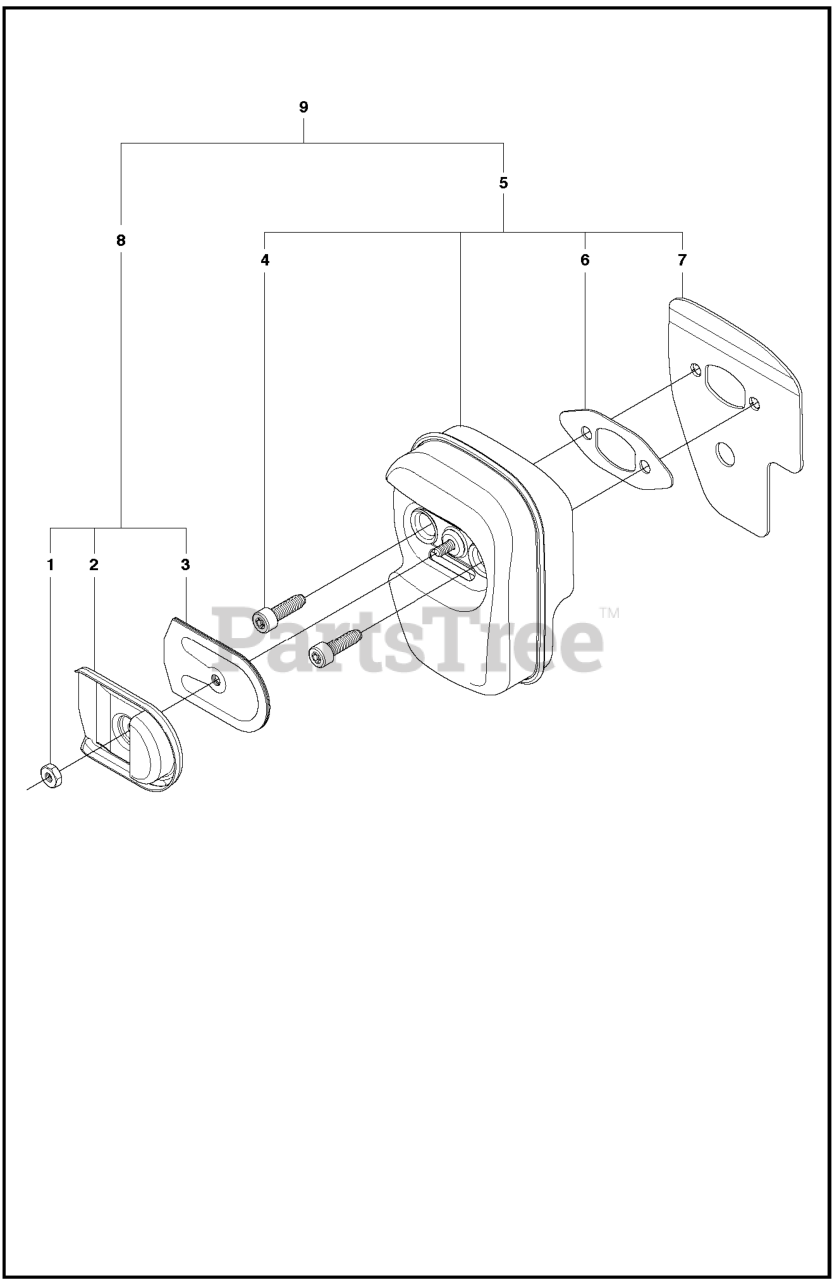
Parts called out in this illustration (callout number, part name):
1	NUT 10MM BRASS
2	EXHAUST PLATE
3	SCREEN ARRESTOR
4	SCREW MUFFLER
5	MUFFLER ASSY
6	GASKET
7	PLATE
8	KIT SPARK ARRESTOR
9	MUFFLER KIT
